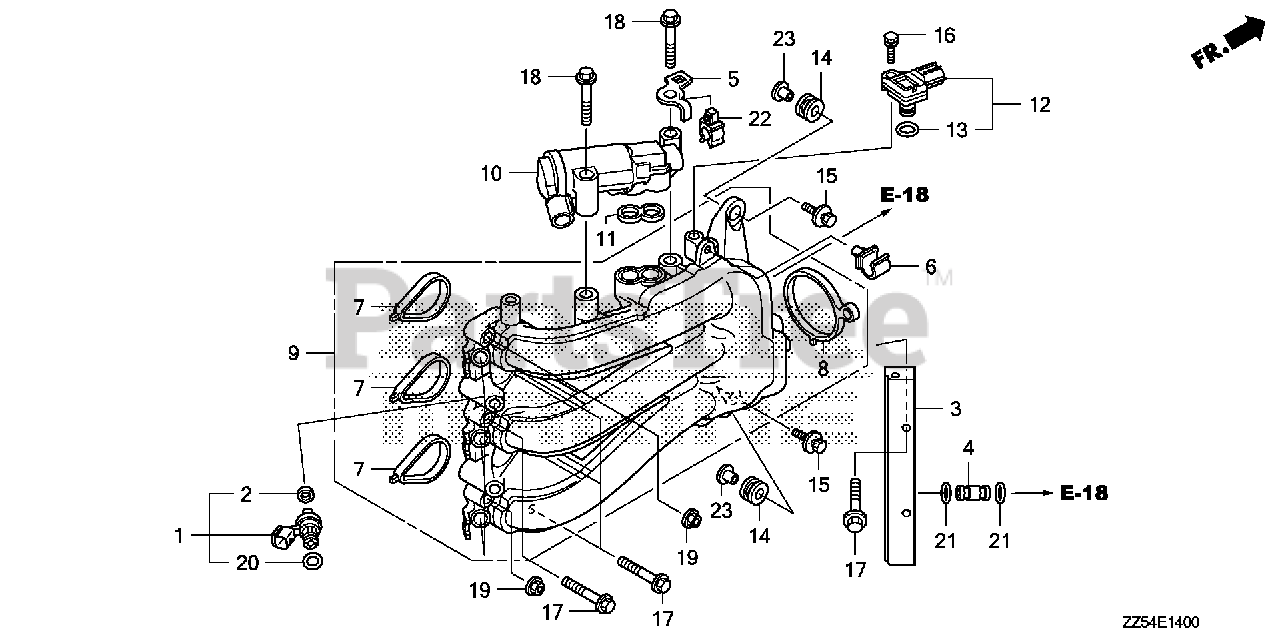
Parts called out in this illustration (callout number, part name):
1	INJECTOR ASSY., FUEL
2	RING, SEAL
3	LINE, FUEL
4	JOINT, FUEL PIPE
5	BRACKET B, TUBE CLAMP
6	CLAMP B, FUEL TUBE
7	GASKET, IN. MANIFOLD
8	GASKET, THROTTLE BODY
9	MANIFOLD, INLET
10	VALVE ASSY., ELECTRONIC AIR CONTROL
11	GASKET, ELECTRONIC AIR CONTROL VALVE
12	SENSOR ASSY., MAP
14	GROMMET, CASE (LOWER)
15	BOLT-WASHER (6X25)
16	BOLT-WASHER (5X18)
17	BOLT, FLANGE (6X32)
18	BOLT, FLANGE (8X45)
19	NUT, FLANGE (6MM)
20	O-RING (7.3X2.2)
21	O-RING (7.8X1.9) (ARAI)
22	CLIP, TUBE (3.5)
23	COLLAR, MODULE IGNITION CONTROL CASE (CDI)
